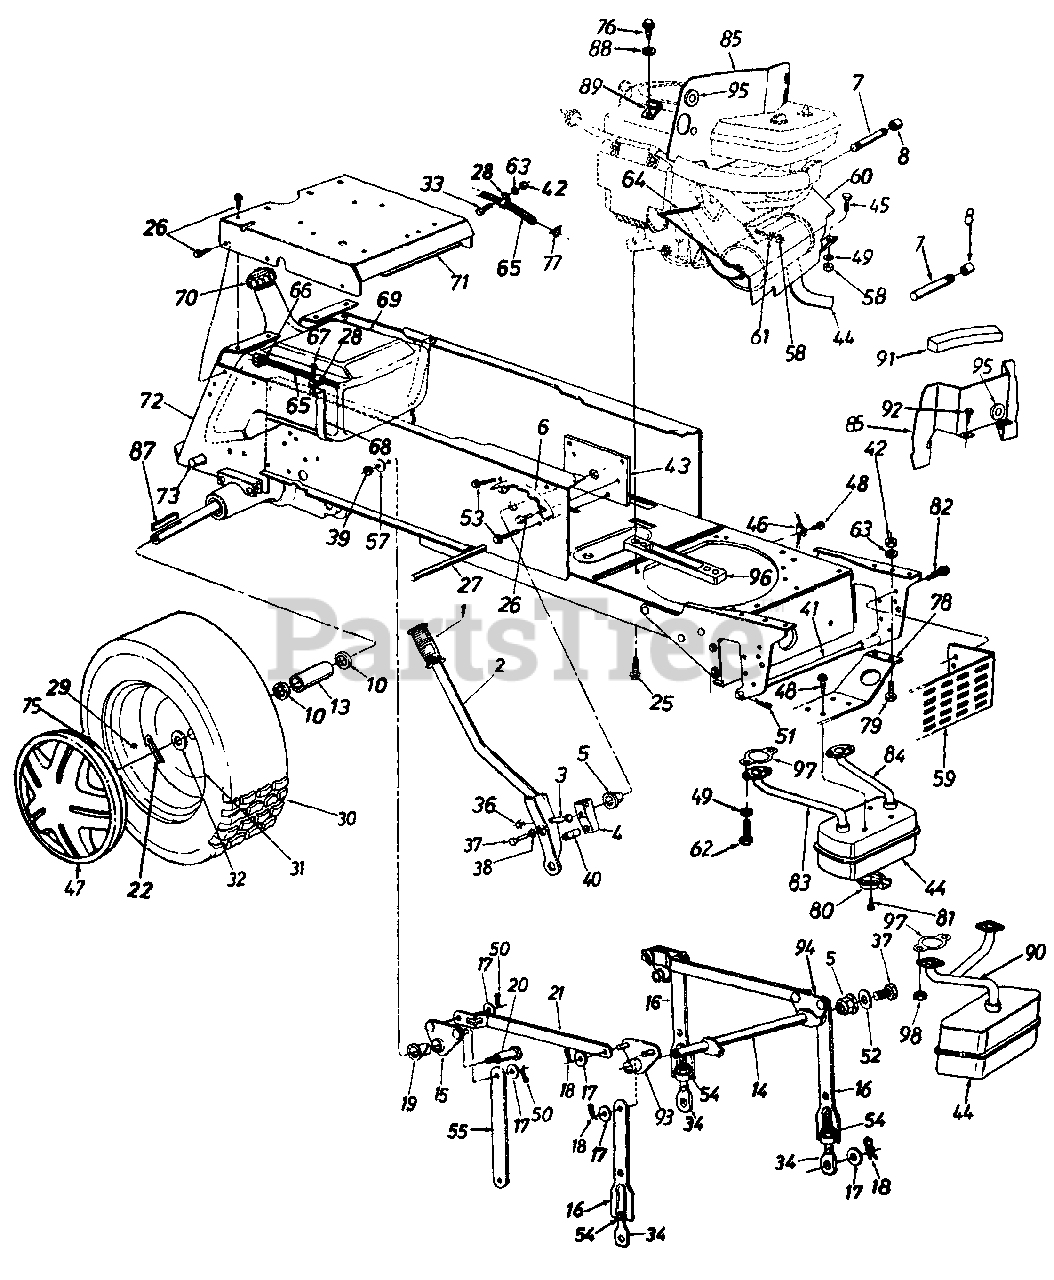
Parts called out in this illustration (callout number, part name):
1	Grip
4	Lift Shaft Drive
5	Plastic Hex Brg. 5/8" I.D.
8	Oil Drain Cap
10	Fl-Wash. 1.03" I.D. x 1.62" O.D.
13	Spacer 1" I.D. x 1.25" O.D.
14	Lift Shaft Ass'y.
15	Lift Pivot Brkt. Ass'y.
17	Fl-Wash. 1/2" I.D. x 1.00" O.D. x .090"
18	Hairpin Cotter
19	Flange Brg .63" I.D.
20	Shld. Bolt 5/8" Dia. x .96" Lg. 3/8-16
25	Hex Tap Scr. 3/8-16 x 1.25" Lg.
26	Hex Thd. Rolling Scr. 5/16-18 x .75" Lg.
27	Running Board Rod
28	Clamp
29	Air Valve
33	Hex Bolt 1/4-20 x .62" Lg.
34	Eye Bolt Adj. Link 1/2-13 Thd.
36	Hex Cent. L-Nut 5/16-18 Thd.
37	Hex Bolt 5/16-24 x .62" Lg.
39	Hex Top L-Nut 3/8-16 Thd.
40	Compression Spring
41	Deck Connecting Rod
42	Hex Nut 1/4-20 Thd. (Gr. 5)
45	Hex Bolt 5/16-18 x .75" Lg.
46	Mounting Clamp
47	Hub Cap
48	Hex TT-Tap Scr. 1/4-20 x .5" Lg.
49	L-Wash. 5/16" I.D.
50	Cotter Pin .09 Dia. x 1.0" Lg.
51	Int. Cotter Pin
52	Flat Wash .34" I.D. x 1.12" 0 D. x .125"
53	Hex AB-Tap Scr. 5/16-24 x .5"
54	Hex Nut 1/2-13 Thd.
57	Bell-Wash .4" I.D. x 1.13" O.D.
58	Hex Nut 5/16-18 Thd.
59	Heat Shield
60	Front Heat Shield
61	Spec. L-Wash. 5/16" I.D.
62	Hex Bolt 5/16-18 x 1" Lg.
63	L-Wash. 1/4" I.D.
64	Trim Strip 12" Lg.
65	Fuel Line 60" Lg.
66	Hose Clamp
67	Hex AB-Tap Scr. 1/4 x .62" Lg.
68	Fuel Tank Strap
69	Gas Tank
70	Gas Gauge
71	Seat Plate
75	Spring Clip
76	Truss Mach. B-Tap Scr. #10 x .5" Lg
77	Hose Clamp
78	Muffler Mounting Brkt.
79	Hex Bolt 1/4-20 x .85" Lg.
80	Muffler Deflector
81	Hex F-Tap Scr. #8 x .32" Lg.
82	Hex TT-Tap Scr. 5/16"-18 x .62"
83	Exhaust Tube - R.H.
84	Exhaust Tube - L.H.
87	Sq. Key 1/4" x 3" Lg.
88	Fl-Wash .188" I.D. x .438" O.D.
89	Clamp
90	Exhaust Pipe
91	Foam Seal (2 on Hood)
92	Hex Tap Scr. #8-32 x .5" Lg.
93	Pivot Brkt. Ass'y.- R.H.
94	Pivot Brkt. Ass'y.- L.H.
95	Grommet
96	Engine Mtg. Spacer
97	Gasket
98	Flange Nut M8 x 1.25 Thd.
